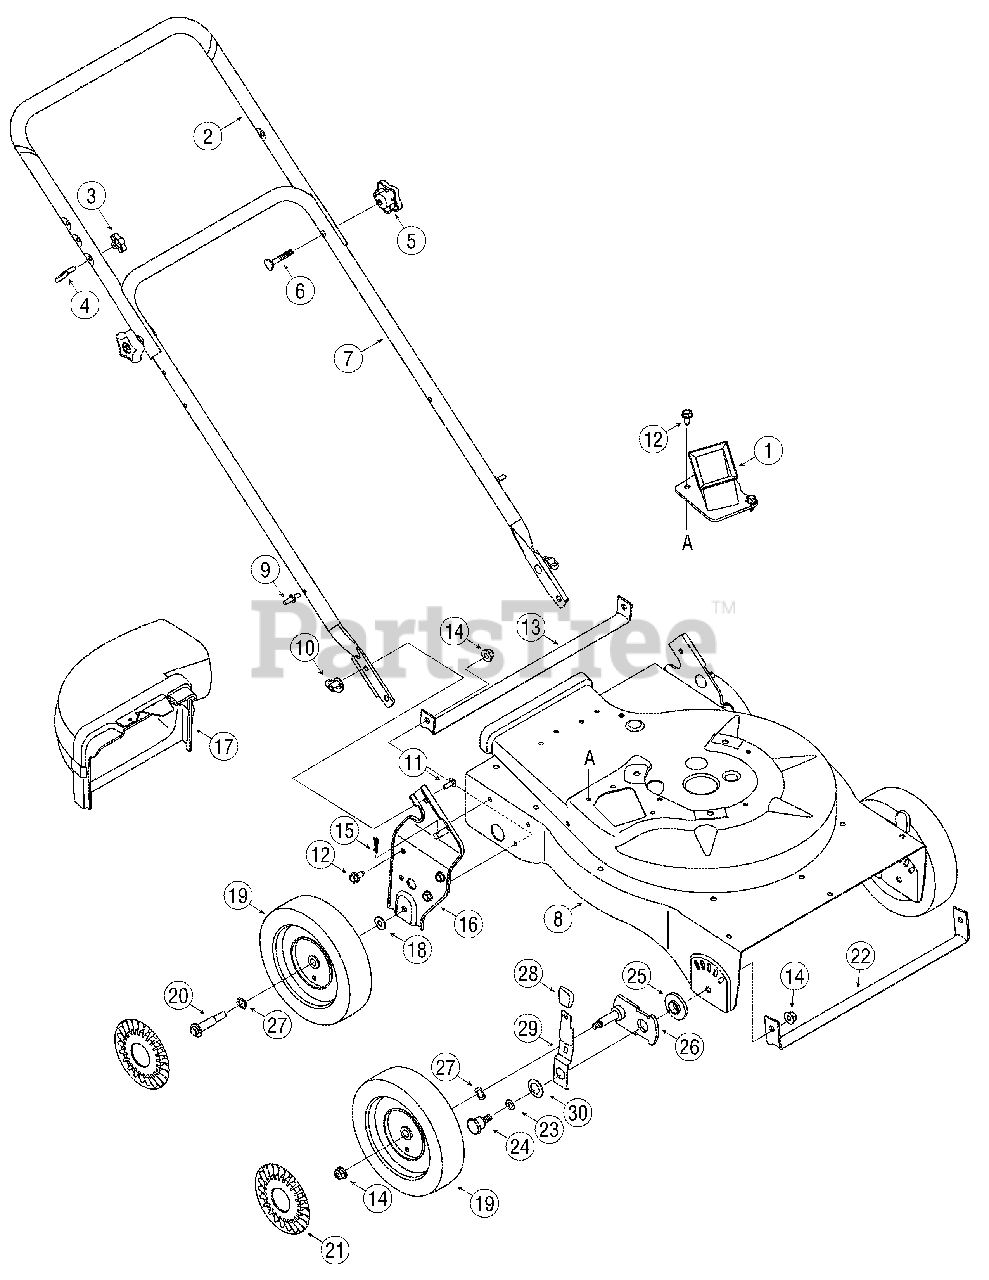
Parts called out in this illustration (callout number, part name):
4	Eye Bolt
5	Star Knob, 5/16-18
6	Carriage Bolt
9	Studs
10	Wing Nut 1/4-20
11	Carriage Screw 1/4-20 x.75
12	Screw, 5/16-12 x.750
14	Flange Lock Nut, 3/8-16
15	Cotter Pin
17	Blower Chute Assembly
18	Bell Washer.401 ID x.870 OD
19	Wheel, 8 x 2.125
20	Shoulder Screw 3/8-16
21	Hubcap
23	Thrust Washer.375 ID x.70 OD
24	Shoulder Screw, .750 ID x .500
25	Height Adjustment Bearing
26	Pivot Arm Assembly
27	Wave Washer.531 ID x.781 OD
28	Height Adjustment Knob
29	Spring Lever
30	Bell Washer.760 ID x.25OD
